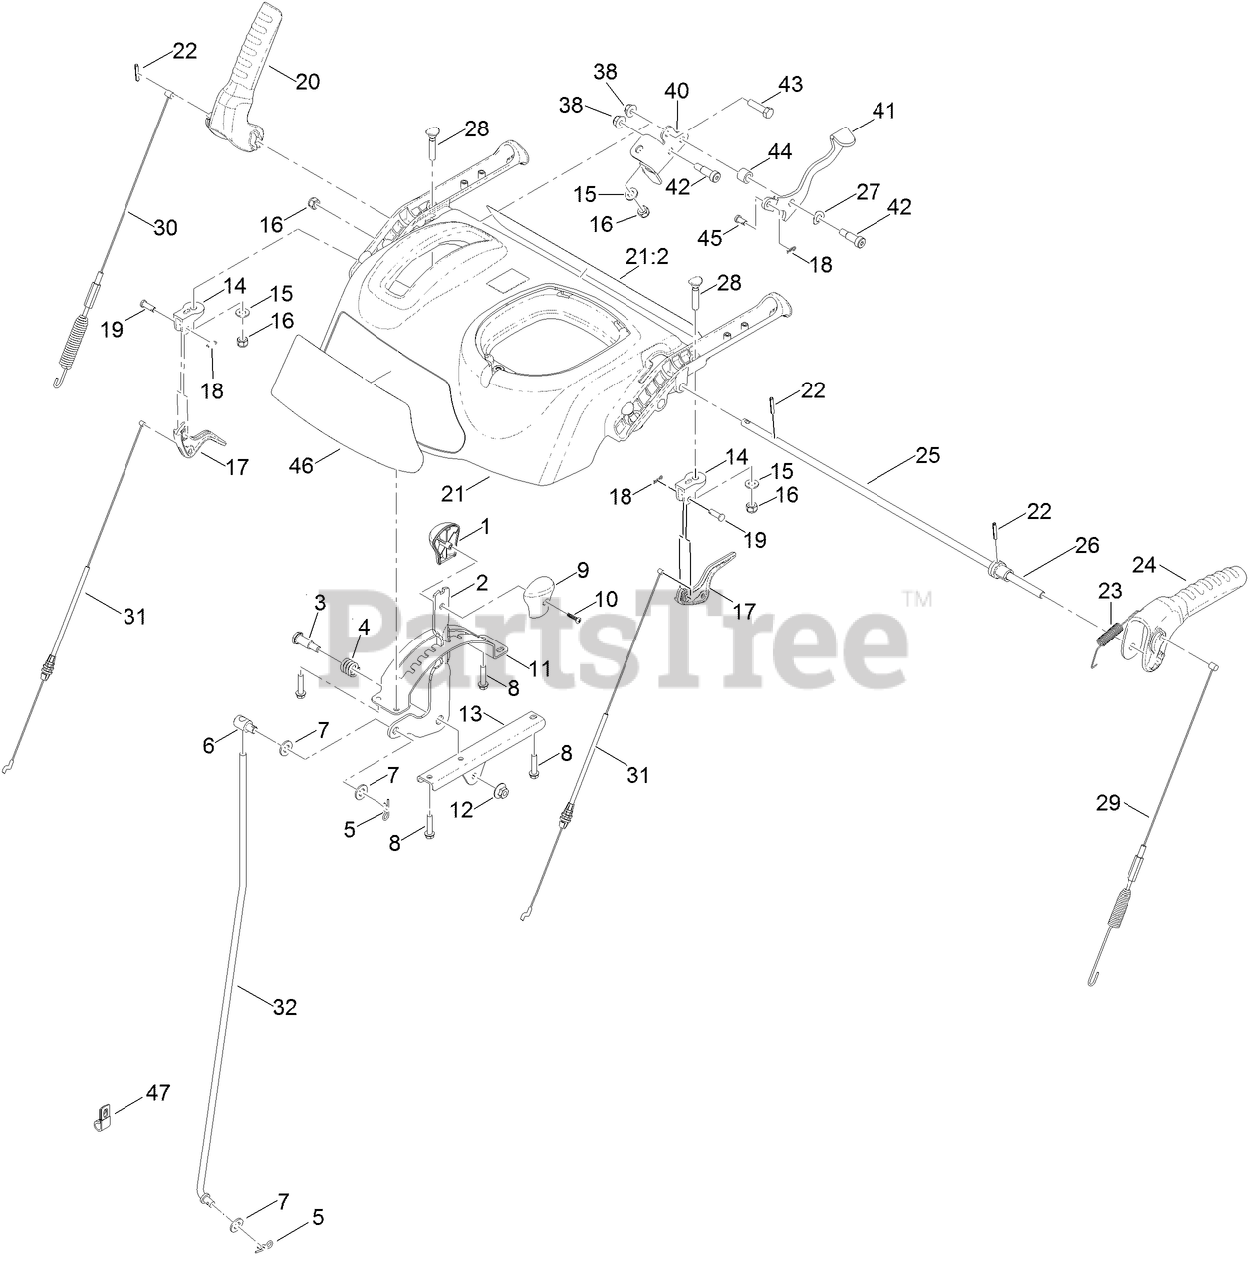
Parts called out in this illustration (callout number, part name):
1	KNOB-SHIFT, RH
2	SELECTOR-SPEED
3	SCREW-SHOULDER
4	SPRING-COMPRESSION
5	PIN-COTTER
6	TRUNNION-ROD
7	WASHER-FLAT
8	SCREW-PLASTITE
9	KNOB-SHIFT, LH
10	SCREW-PPH
11	GUIDE-SELECTOR, SPEED
12	NUT-HF
13	BRACKET-SELECTOR, SPEED
14	MOUNT-CLUTCH, LEVER
15	WASHER-FLAT
16	NUT-LOCK, NI
17	LEVER-CLUTCH
18	PIN-HAIR
19	PIN-CLEVIS
20	LEVER-AUGER
21	CONTROL PANEL ASM
21:2	DECAL-CONTROL, PANEL
22	PIN-SPRING
23	SPRING-TENSION
24	LEVER-TRACTION
25	ROD-LOCKOUT
26	CAM-LOCKOUT
27	WASHER-SPRING
28	SCREW-HANDLE
29	CABLE-TRACTION
30	CABLE-AUGER
31	CABLE-CLUTCH
32	ROD-SHIFT
38	NUT-HF, NI
40	BRACKET-LEVER, BROOM ANGLE
41	LEVER-THUMB, BROOM ANGLE
42	SCREW-SHOULDER, HSH
43	SCREW-HH
44	TUBE-SPACER
45	PIN-CLEVIS
46	DECAL-TORO, POWER BROOM
47	CLIP-LOOM
